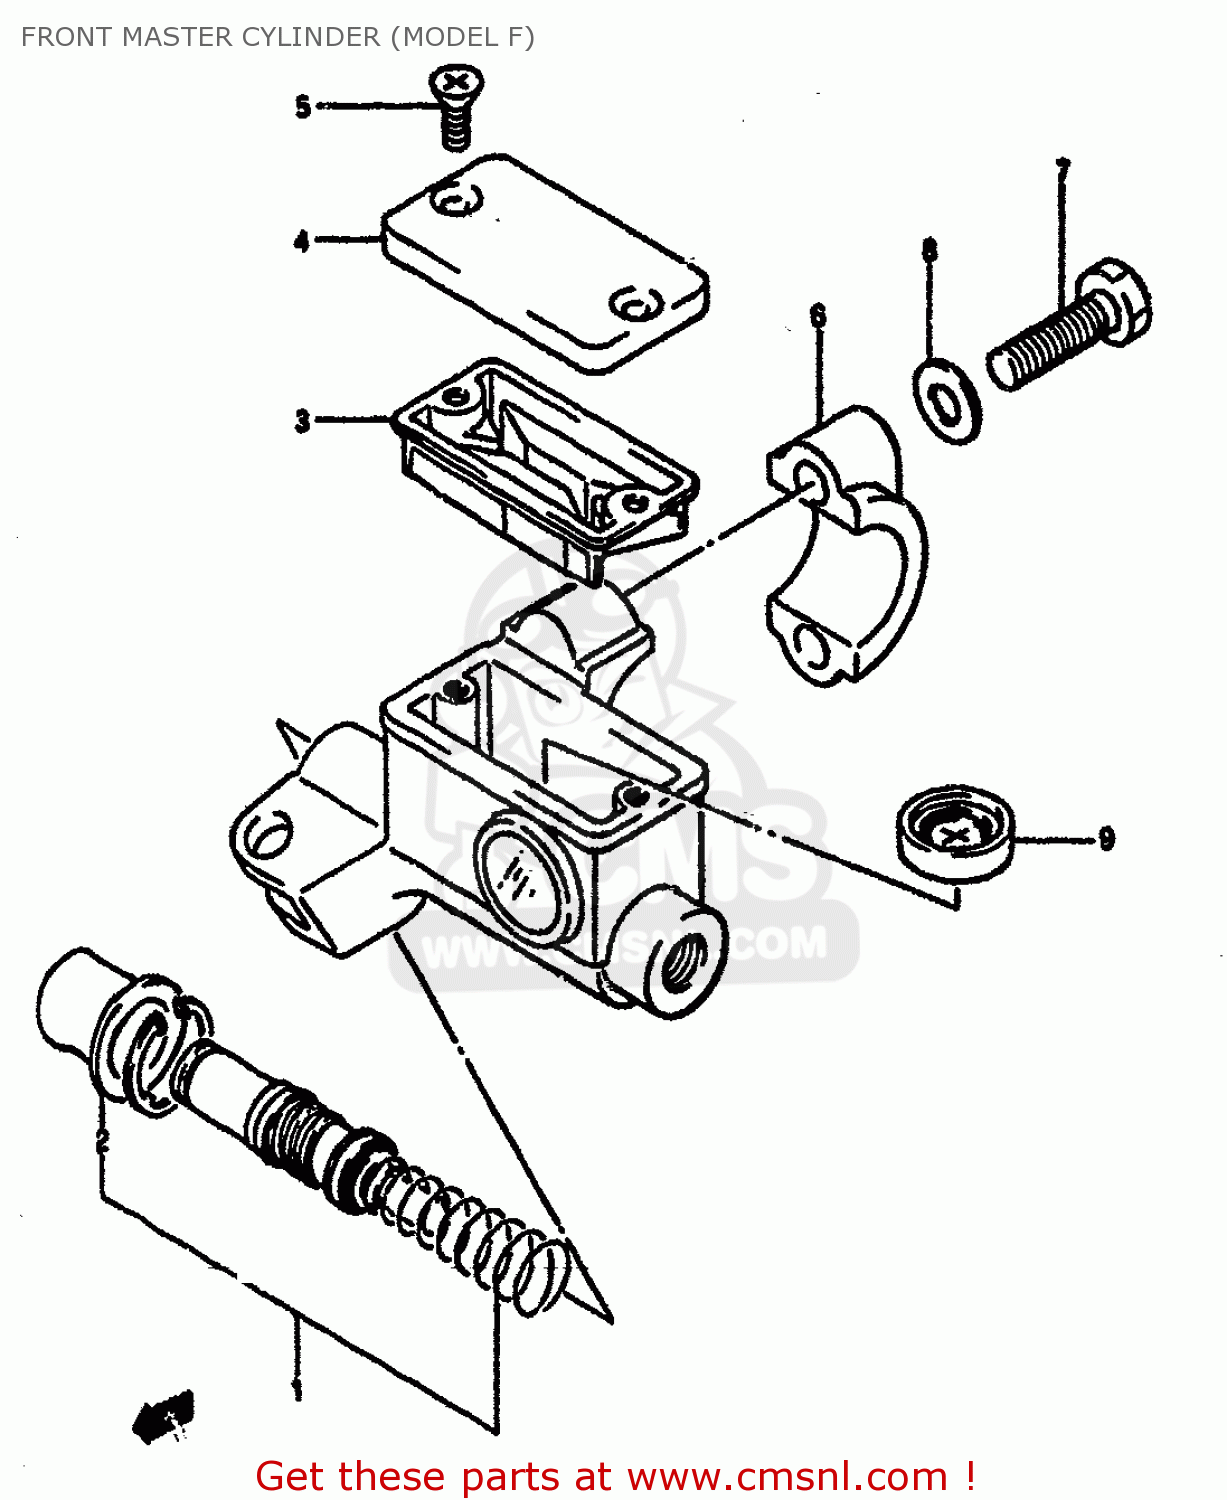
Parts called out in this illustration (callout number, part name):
1	PISTON/CUP SET,FR MASTER
2	BOOT
3	DIAPHRAGM
4	CAP
5	SCREW
6	HOLDER,MASTER CYLINDER
7	BOLT
8	WASHER
9	SEPARATOR
